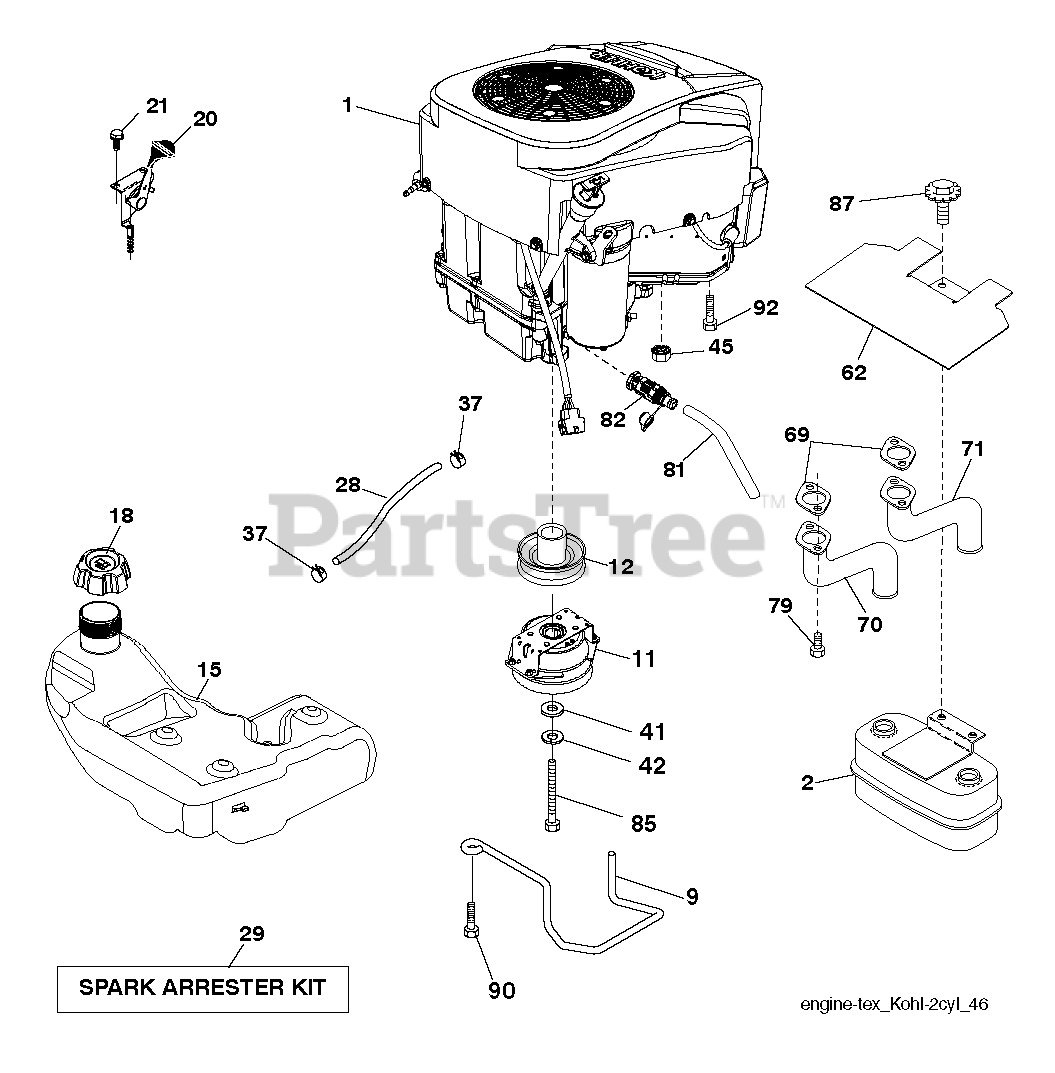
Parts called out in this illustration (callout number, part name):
2	MUFFLER.ASM.TWN.EXTNDED.DFLCTR
9	KEEPER BELT ENGINE
11	Clutch, Ogura 5.0Pd Gt1.5A-Eh01
12	PULLEY ENGINE
15	TANK.ASM.4.GAL.EPA.ONE.PORT
18	Fuel Cap Assembly, 3" Black
20	THROTTLE CONTROL
21	SCREW.#10 X 0.750.BOS (2 2)
28	LINE.FUEL.64"REAR.EMIS
29	KIT.SPARK ARRESTOR(392390 B&S)
37	HOSE CLAMP
42	LOCKWASHER
45	NUT
62	SHIELD.HEAT.MUFFLER
69	GASKET.EXHAUST.KOHL.CV18-CV26
70	Exhaust Pipe, LH CV18/20
71	Exhaust Pipe, RH CV18/20
79	SCREW.SOCKET HD.5/16-1
81	TUBE, DRAIN OIL ASM.
82	VALUE.OIL.DRAIN
85	Hex Bolt, 7/16-20 X 3.0 Gr5
87	BOLT, 5/16-18 X 1 3/4
90	SCREW 3/8-16X1
92	SCREW 3/8-16X1
